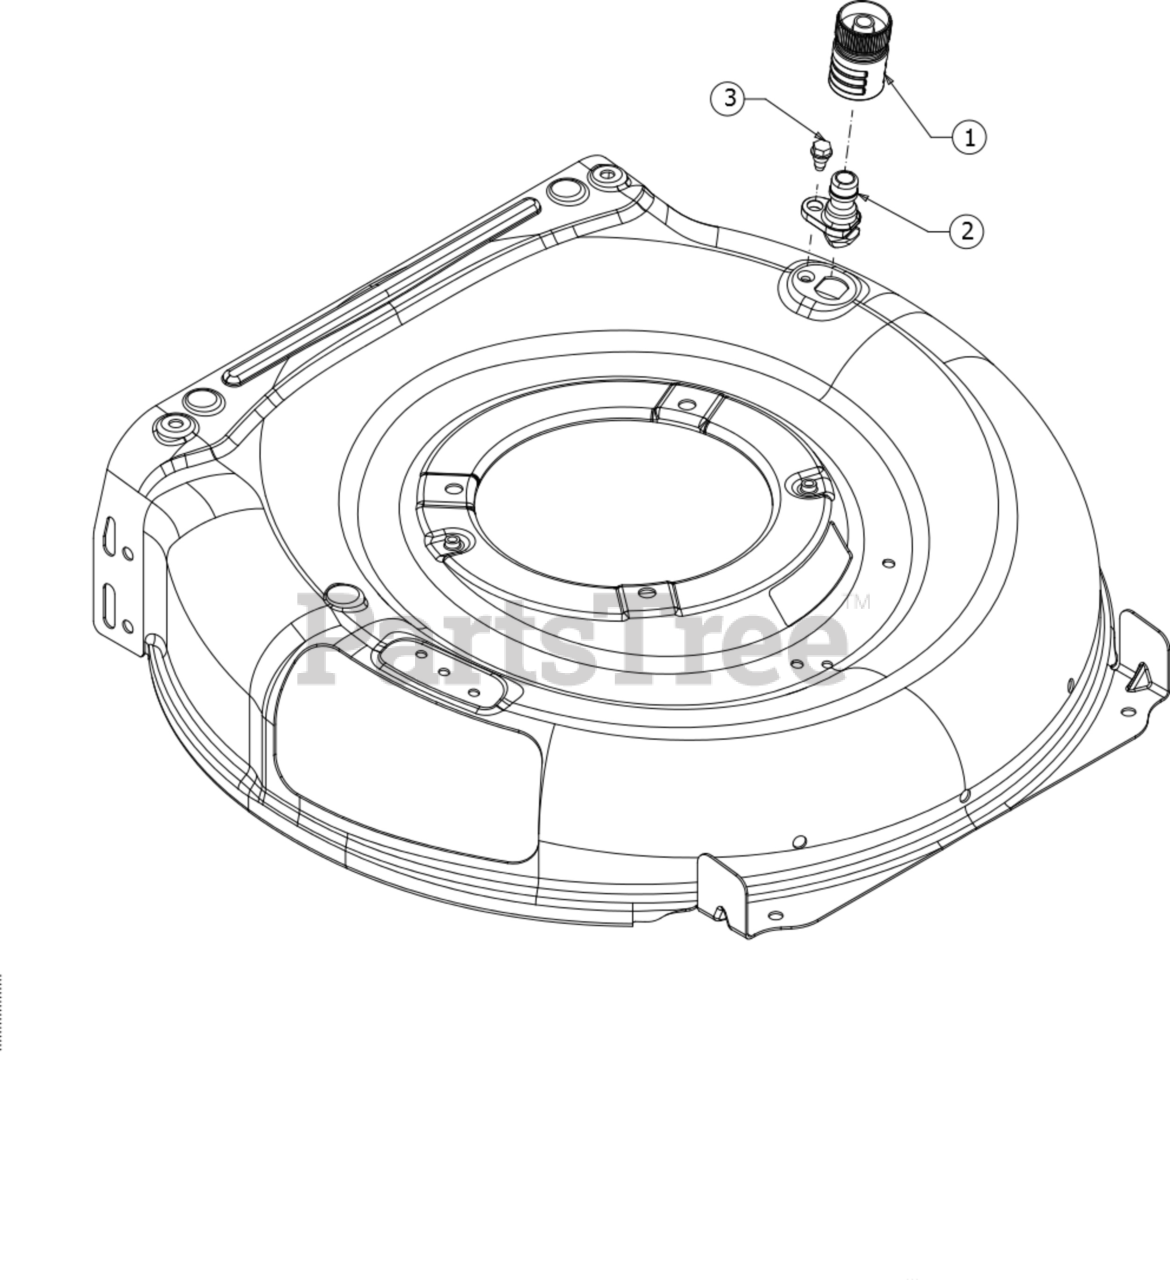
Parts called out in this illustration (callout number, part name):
1	WATER NOZZLE
2	DECK WASH NOZZLE
3	SHOULDER SCREW 1/4-20 X .50
